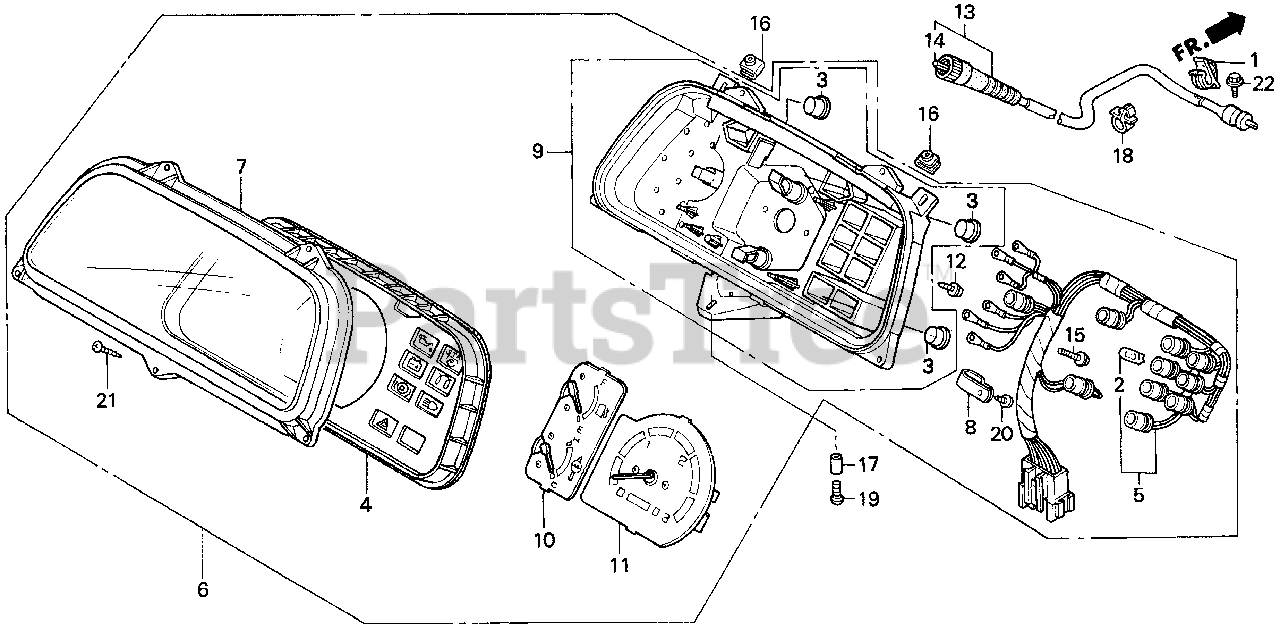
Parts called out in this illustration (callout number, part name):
1	CLIP B, HARNESS
2	BULB, WEDGE BASE (12V1.7W) (NIPPON SEIKI)
4	PLATE, REFLECTING
6	METER ASSY., COMBINATION
7	LENS, METER
9	CASE, METER
10	METER, FUEL & TEMPERATURE
11	TACHOMETER
12	SCREW, FLANGE (3X6)
13	CABLE ASSY., TACHOMETER
14	CABLE (INNER) (NOT AVAILABLE)
15	SCREW-WASHER (3X22)
16	NUT, FLOATING (5MM)
17	COLLAR (5X3.5)
18	CLIP, TUBE (12MM)
19	SCREW, PAN (5X14)
20	SCREW, TAPPING (4X12)
21	SCREW, TAPPING (4X20)
22	BOLT, FLANGE (6X25)
